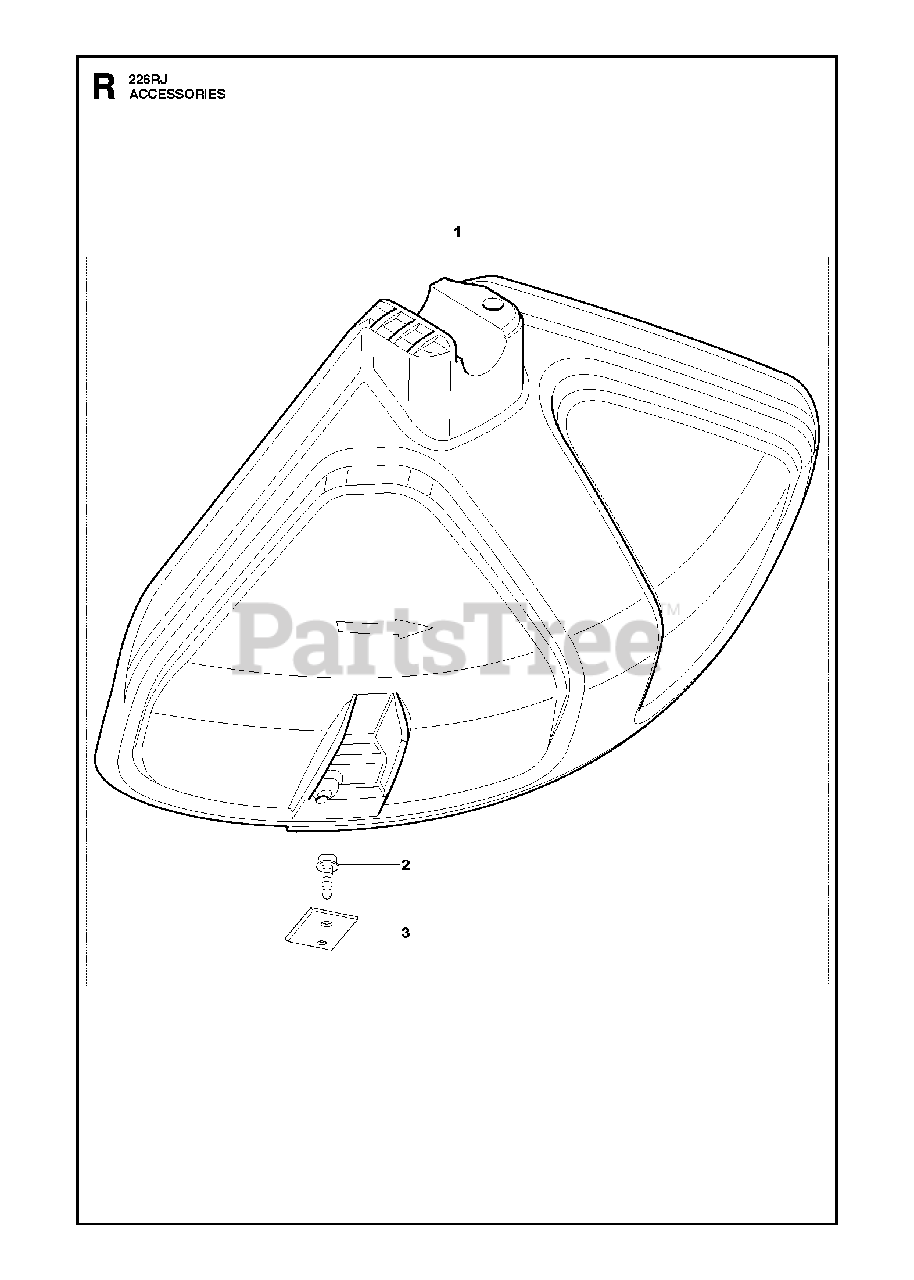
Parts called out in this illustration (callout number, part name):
1	GRASS SHIELD
2	SCREW
3	LINE CUTTER
